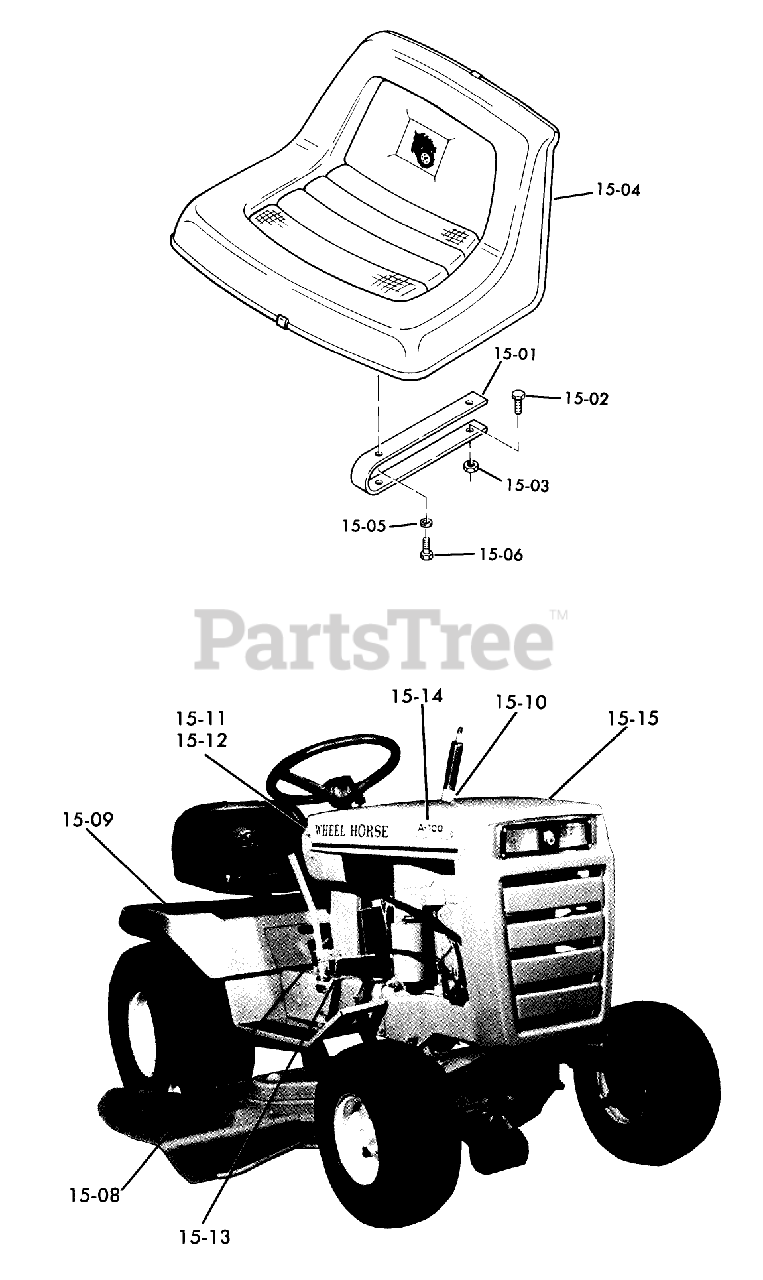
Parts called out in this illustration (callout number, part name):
15-10	DECAL-HAND LIFT
15-13	Decal-Off/On
15-15	Decal-Hood A-100 LH
